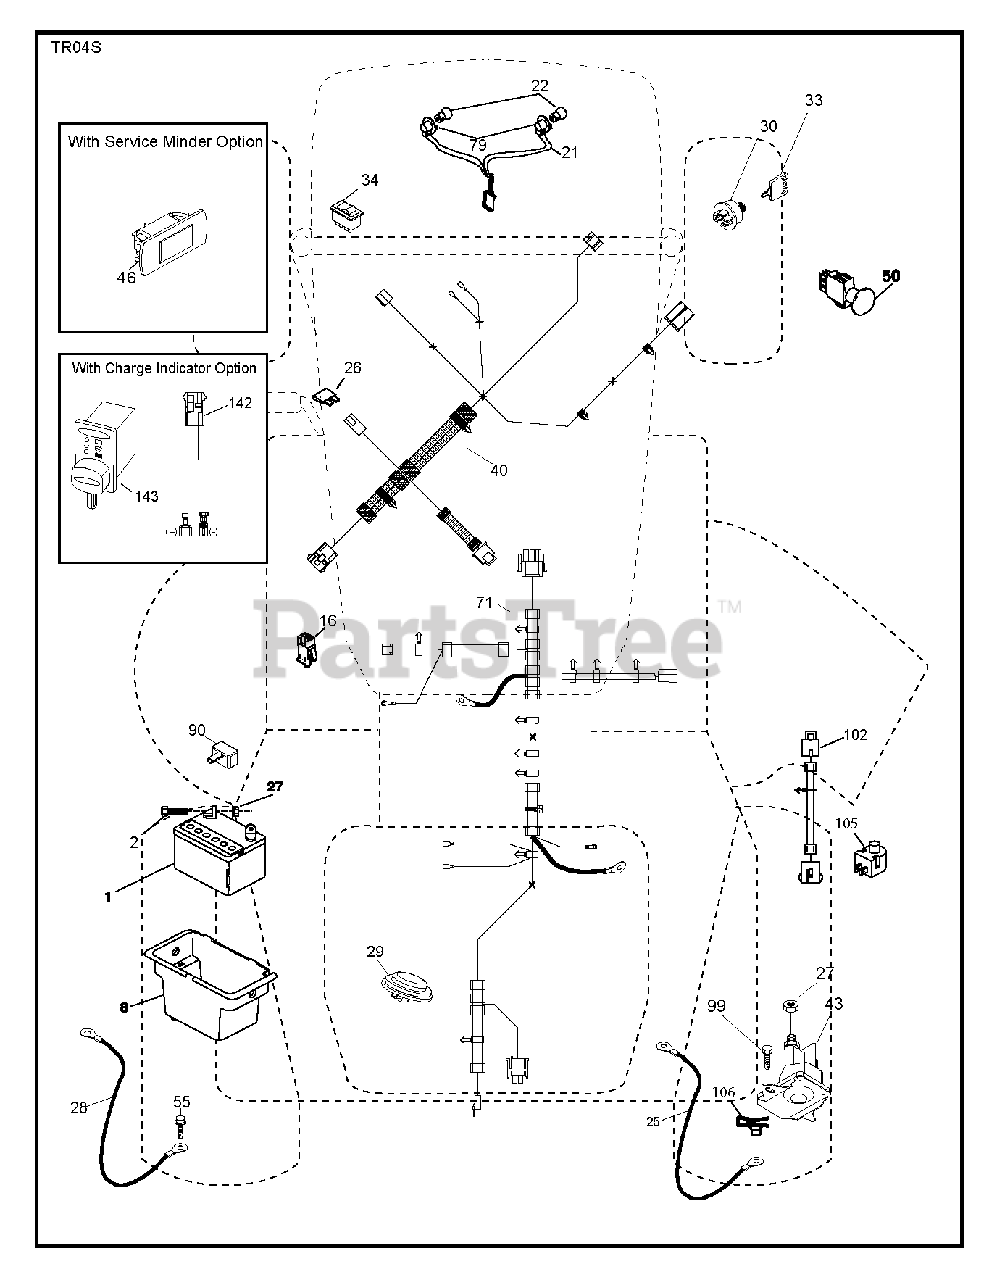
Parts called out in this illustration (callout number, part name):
1	Battery, Dry 30 Amp
2	BOLT.HEX.1/4.X.3/4.DICHROMATE
8	BOX.BATTERY.MNT.REAR.L
16	SWITCH INTERLOOK PUSH-IN
21	HARNESS.LIGHT W/4152J BULBS
25	CABLE.BATT.RED.8GA.17
26	FUSE 20AMP
27	NUT
28	CABLE.GROUND.REAR.BATTERY.8G
29	SWITCH.SEAT.DELTA.OPC.
30	SWITCH.IGN.DELTA.W.LGH.ROS
33	KEY.CHAIN.BLISTER.PACK.GEN.INT
40	HARNESS.TEX.DASH.ELEC.REAR BAT
43	SOLENOID.W/BRASS.PLUNGER
46	RP GUAGE.SRVCMNDR.HRMTR.
50	RB PTO.SWITCH.8 TERMINAL.BLACK
55	SCREW 5/16"
71	HARNESS.TEX.CHSSIS.REAR.BATT
79	BULB HOLDER ASM.
90	COVER.TERMINAL.BATTERY
99	SCREW HEXWSHR 1/4-20X3/4
102	HARNESS PIGTAIL PCH TEX ROS
105	REVERSE SWITCH
106	1/4-20 U NUT
